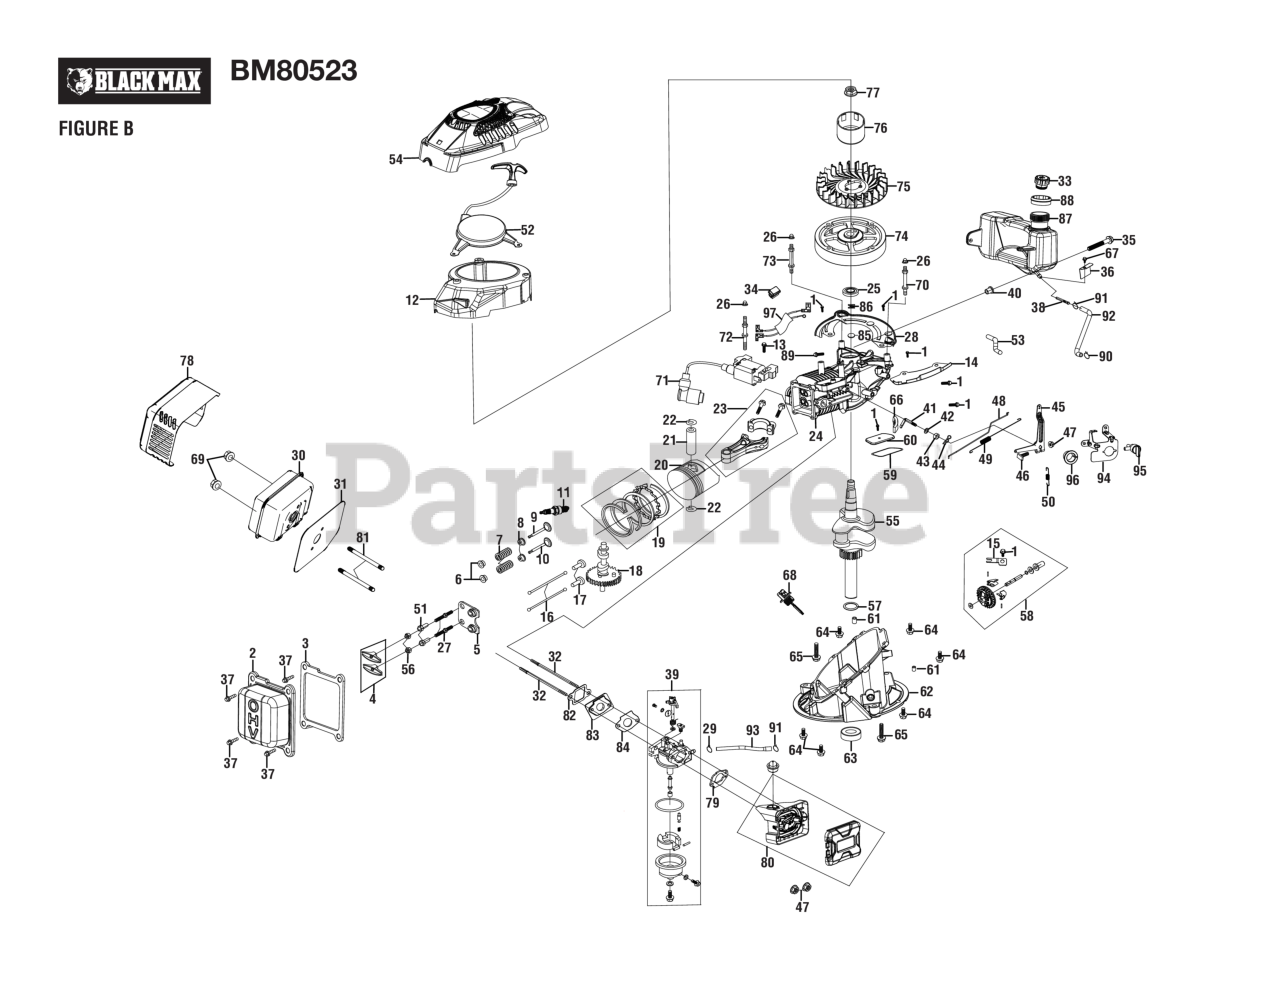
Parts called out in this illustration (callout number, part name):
1	BOLT M6X12 BOLT M6X12
2	COVER COMP,CYLINDER HEAD
3	PACKING,HEADCOVER
4	ARM, ROCKER
5	PLATE,PUSH ROD GUIDE
6	SEAT, VALVE SPRING,IN
7	SPRING,VALVE
8	RETURNER,INTAKE VALVE
9	VALVE, INTAKE
10	VALVE EXHAUST
12	START SMALL CAP
14	WIND SHIELD,LH
15	PLATE,GOVERNOR
17	LIFTER,VALVE
18	CAMSHAFT ASSY
19	SCRAPER RING SET ,PISTON
21	PIN, PISTON
22	CLIP, PISTON
23	ROD ASSEMBLY, CONNECTING
27	ADJUSTER ROCKER ARM
29	FUEL PIPE CLAMP 7.5
30	MUFFLER ASSY
31	GASKET,EXHAUST
33	FUEL TANK CAP
34	SWITCH ASSY
36	Wind Deflector
39	CARBURETOR ASSY
40	BUSHING,FUEL TANK
41	SHAFT,GOVERNOR ARM
42	WASHER,GOVERNOR ARM SHAFT
43	SEAL,GOVERNOR ARM SHAFT
45	GOVERNOR ARM
46	BOLT,GOVERNOR ARM
47	HEXAGON NUT WITH FLANGE
48	ROD,GOVERNOR
49	SPRING,THROTTLE RETURN
50	SPRING,GOVERNOR
52	Recoil Start Assembly
53	TUBE,BREATHER
54	Shroud Cover
55	CRANKSHAFT ASSY
57	WASHER,CRANKSHAFT
58	GOVERNOR ASSEMBLY
59	GASKET,BREATHER CHAMBER
60	CAP,BREATHER CHAMBER
61	DOWEL PIN,CASECOVER
62	Crankcase Cover Assembly
66	FILTER,BREATHER
67	Cross Screw (M4 x 8 mm)
70	BOLT STUD,RECOIL STARTER
71	IGNITION COIL ASSY
72	BOLT STUD,IGNITION COIL
73	BOLT STUD,RECOIL STARTER
74	FLYWHEEL ASSEMBLY
75	FAN,RECOIL STARTER
76	PULLEY,STARTER
78	SHIELD, MUFFLER
79	GASKET,AIR CLEANER
80	Air Cleaner Assembly
82	GASKET, INTAKE
83	INSULATOR,CARBURETOR
84	GASKET, CARBURETOR
85	CIRCULAR PLATE
86	BREATHER VALVE SPRING
88	FUEL TANK GASKET
90	Fuel Pipe Clamp
91	Fuel Pipe Clamp
92	FUEL HOSE, TANK TO VALVE
93	FUEL HOSE, VALVE TO CARBURETOR
94	FUEL VALVE BRACKET
96	FUEL SWITCH SEAT
97	FLAMEOUT WIRE
